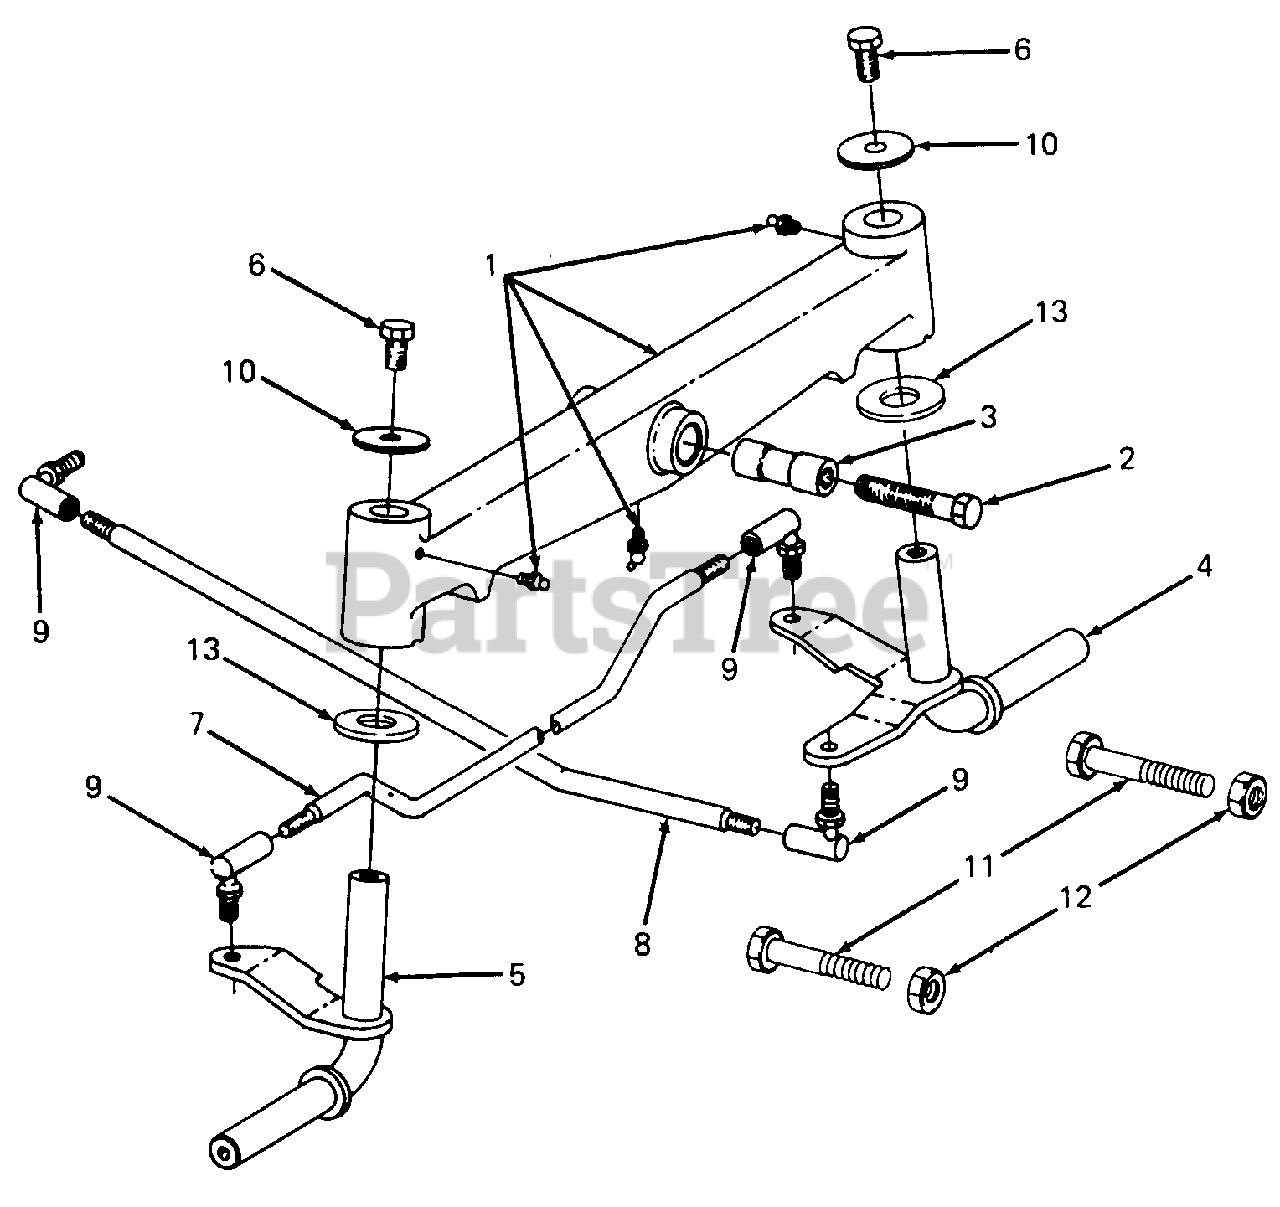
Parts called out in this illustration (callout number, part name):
1	Axle, Front
2	Bolt, 1/2-20 X 4.0 Long GR 5
3	Bushing, Axle Pivot
6	Bolt, 3/8-16 X 3/4 Long GR 5
7	Link, Drag
8	Link, Drag
9	Joint, 3/8-24 Ball Type G
10	Washer, .406 X 1.50 X 11 ga.
11	Bolt, 3/8-16 X 1.25 GR 5
12	Nut, 3/8-16 GR 5
13	Washer, .79 X 1.49 X .06 Hdn
